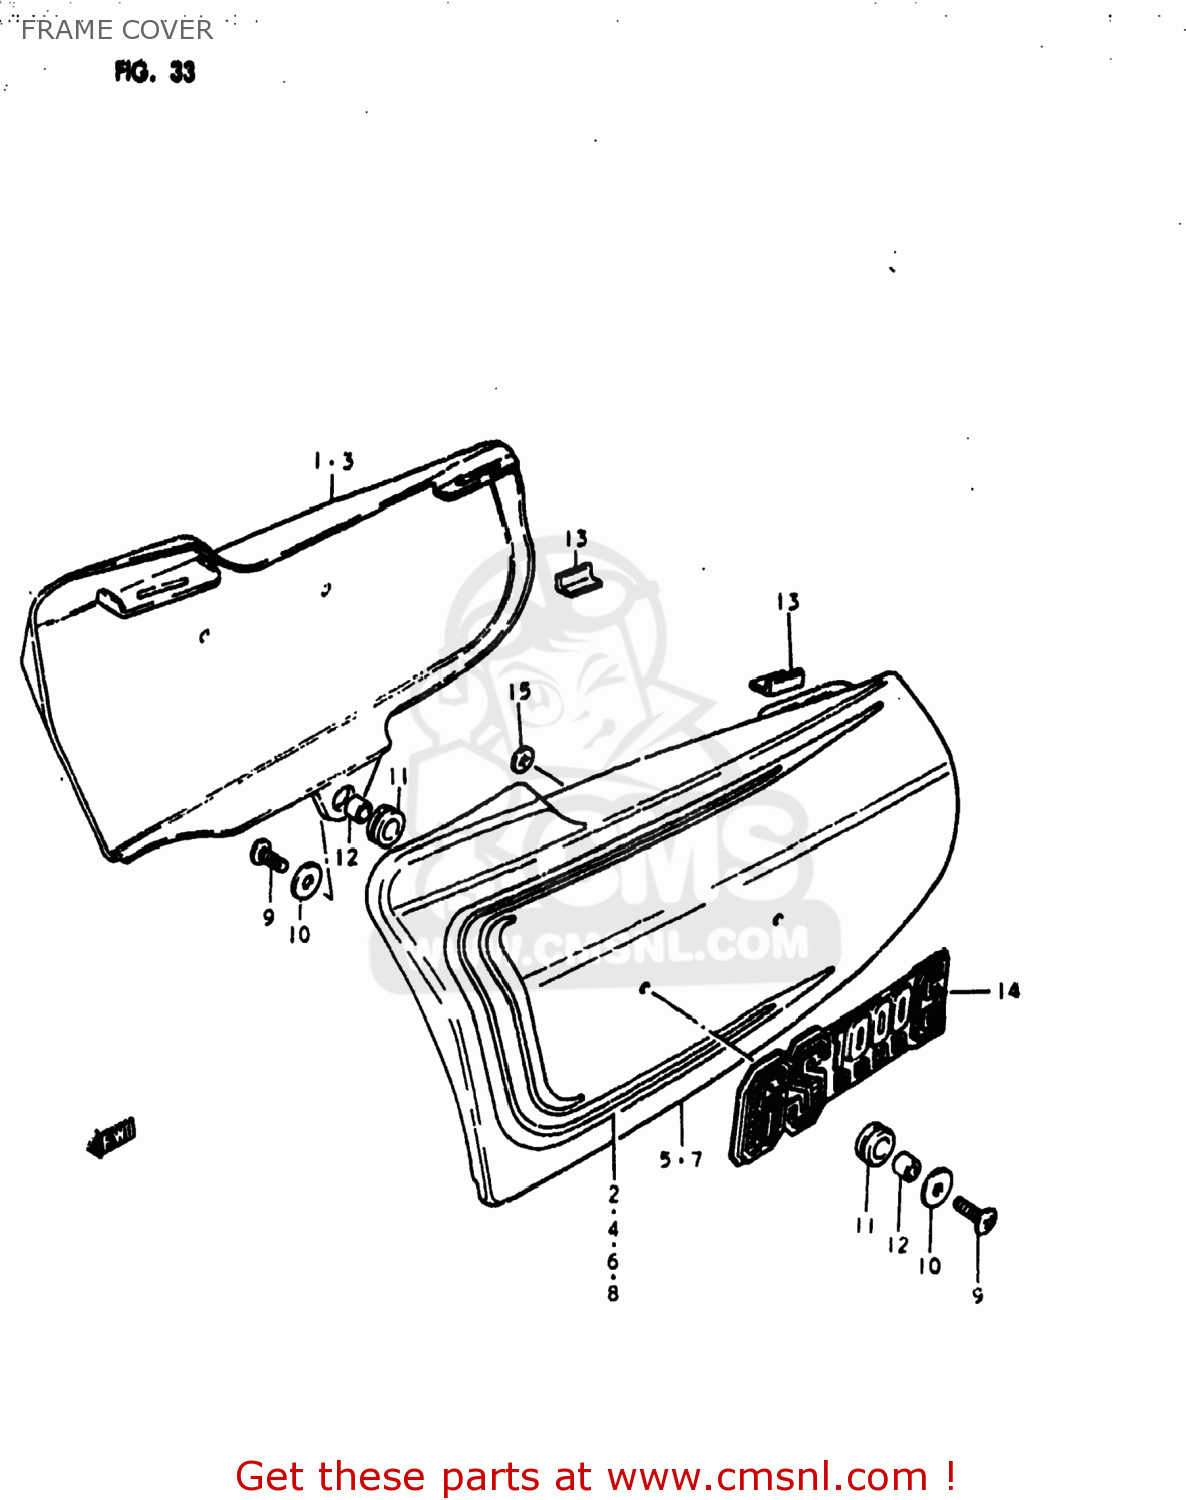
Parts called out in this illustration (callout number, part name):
1	COVER,FRAME,RIGHT
2	TAPE,FRAME COVER
3	COVER,FRAME,RIGHT
4	TAPE,FRAME COVER
5	COVER,FRAME,LEFT
6	TAPE,FRAME COVER
7	COVER,FRAME,LEFT
8	TAPE,FRAME COVER
9	SCREW
10	WASHER (6.5X18X1.6)
11	CUSHION
12	SPACER (6.8X10X10)
13	CUSHION,FRAME COVER
14	EMBLEM,FRAME COVER
15	NUT
